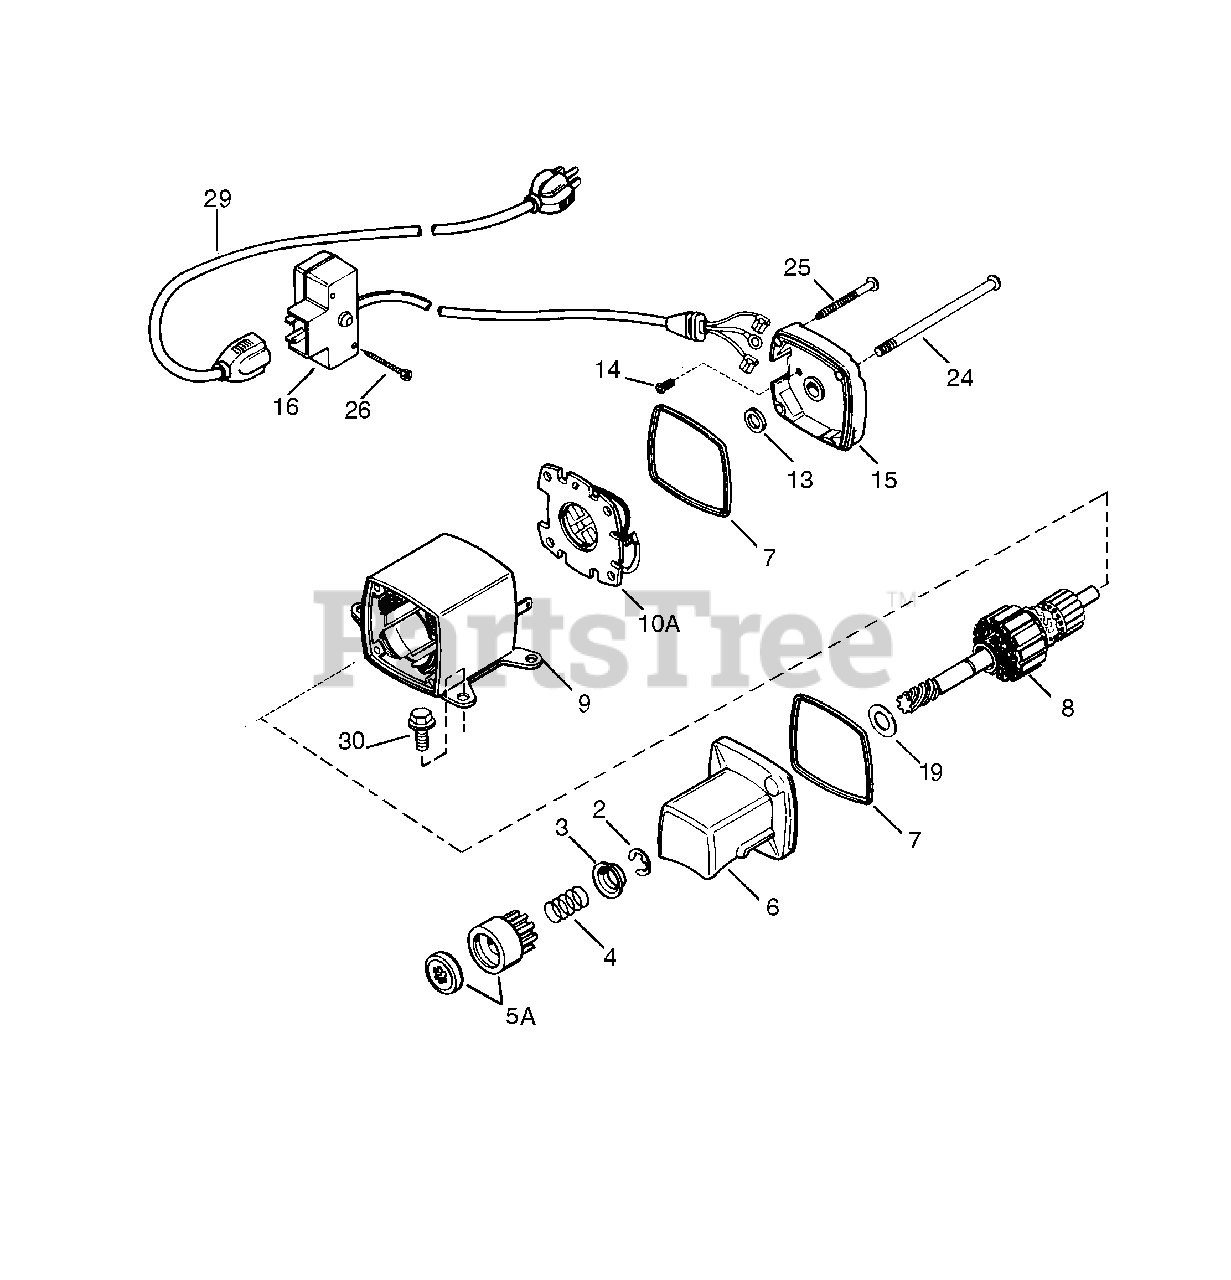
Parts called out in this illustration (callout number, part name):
2	Retainer Ring
3	Spring Retainer
4	Anti-drift Spring
5A	Nut & Gear (Incl. 2)
6	Drive End Cap Ass'y. (Incl. 7)
7	"O" Ring
8	Armature
9	Housing Ass'y. Must Purchase Complete Motor
10A	Brush & Spring Card Ass'y.
13	Thrust Washer
14	Ground Screw
15	Commutator End Cap Ass'y. (Incl. 7)
16	Switch Box Ass'y.
19	Thrust Washer
24	Case Bolt
25	Grounding Screw
26	Screw, 6-32 x 2-1/2"
26	Screw, 12-16 x 5/8"
29	Extension Cord (10'6")
30	Screw, Torx T-30, 1/4-20 x 23/32"
